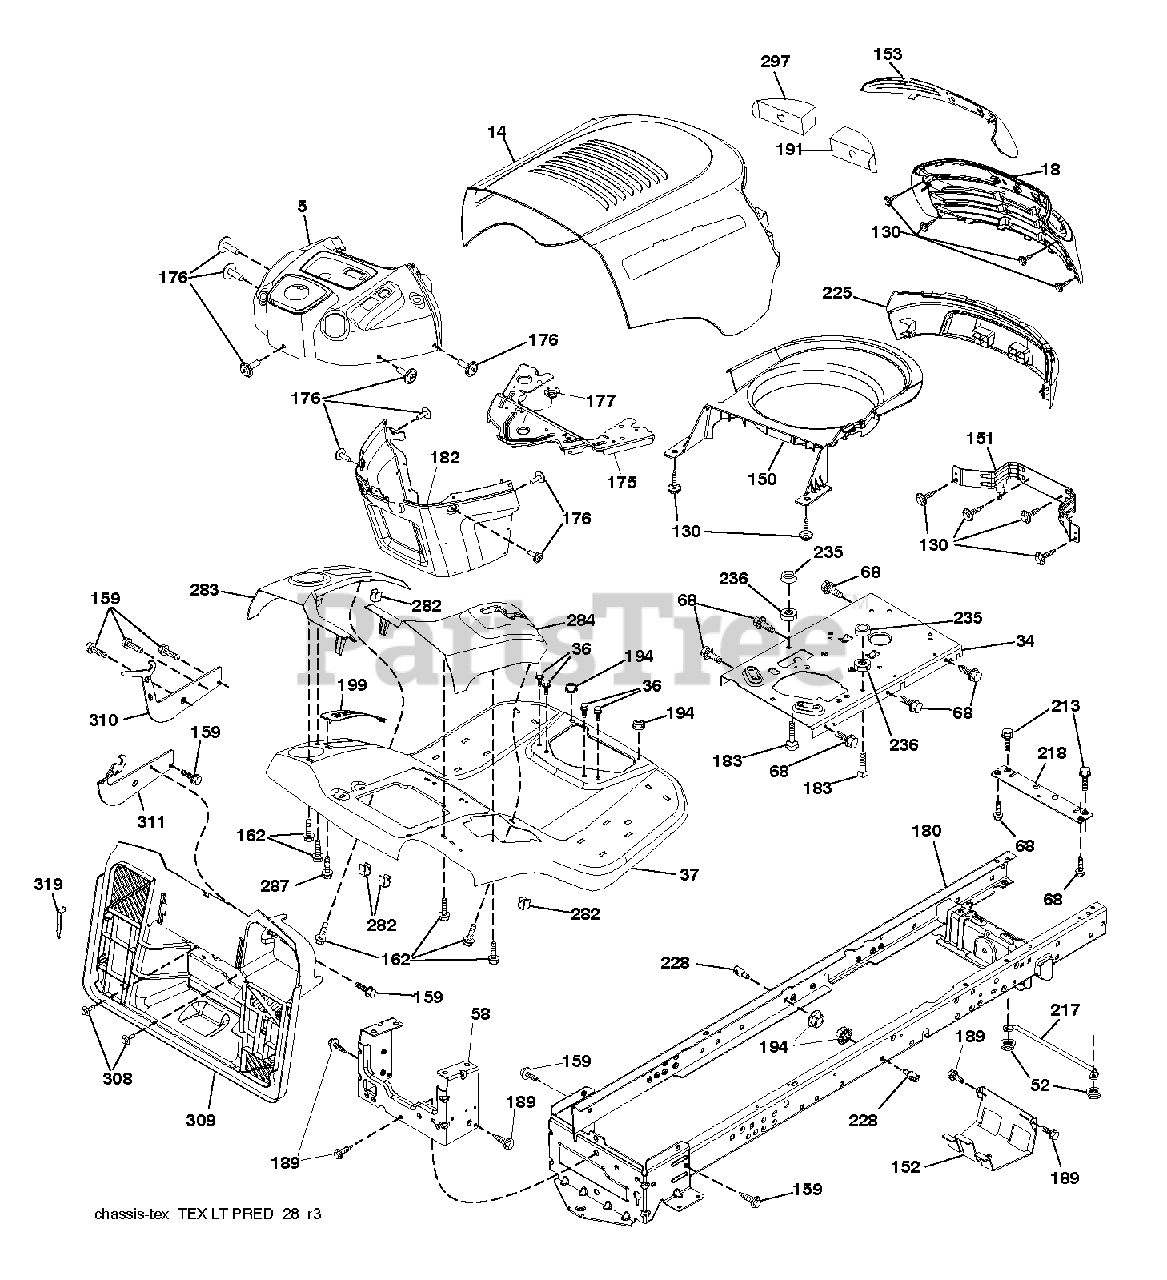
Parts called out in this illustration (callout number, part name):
5	DASH.PRED.LT.CC.ICY.N/SRV.BLK
14	HOOD.PREDATR.LT.U-FRM.TPVNT428
18	GRILLE.SVC.BASE.PREDATOR.LT428
34	PLATE.ENGINE.WELDED.CHASSIS
36	SCREW 5/16"
37	FENDER.TEX.SRD.CRD.BASE
52	LOCKNUT
58	DRAWBAR UPPER 2PC SMALL FENDER
130	SCREW.#10 X 0.750.BOS THREAD
151	BRACKET.PIVOT.ALPHA.LT
152	SHIELD BROWNING
153	LENS.PREDATOR.LT.
159	SCREW, 3/8-16X3/4
162	SCREW.HI-LO.CONSOLE
176	SCREW.#10-24X5/8.RN.QU
177	BUSHING STEERING
180	CHASSIS.WLDMNT.14GA.2PC.18".TI
182	DASH.LWER.PREDATOR/HUSQ.LT
183	BOLT.5/16-18X1-1/4 FULL THD
189	SCREW
191	INSERT.REFLECT.PREDATOR.LT.RH
194	NUT LOCK HEX FLANGE 5/16-18
213	BOLT
217	ROD.PIVOT.HOOD
218	X-PIECE.HOOD.STOP.NON/
228	STUD.FASTNER.W/ANTI-ROTATE
235	SPACER FENDER
236	NUT.CENTERLOCK.5/16-
282	CLIP.RETAINER.CONSOLE.LT.HUSQ
283	CONSOLE.DECKLIFT.LH.SRD.TEXCRD
284	CONSOLE.SHFT.SRD.BGR.R
297	REFLECTOR.INSERT.PRED.LH.LT
308	BOLT, 5/16-18 X 1 3/4
309	BACKPLATE.BAGGER.V2.SRD
319	BRACKET.ACTUATOR.BAGGER.SRD
